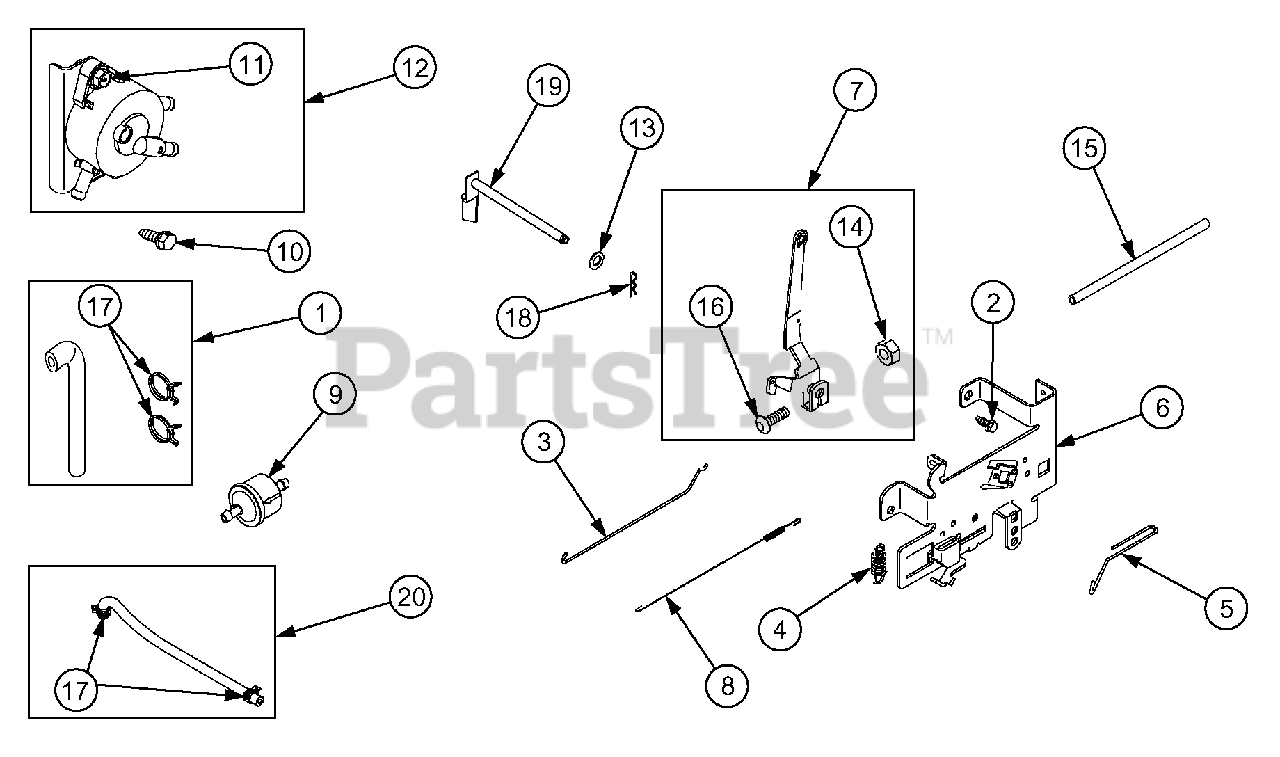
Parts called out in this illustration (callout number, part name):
1	Line, Fuel
2	Screw (Control Bracket)
3	Link, Mechanical Governor
4	Spring, Governor
5	Link, Choke
6	Bracket, Control
7	Control Lever, Governor
8	Spring, Governor Link
9	Filter, Fuel
10	Screw (Fuel Pump)
11	Screw (Fuel Pump)
12	Pump, Fuel
14	Nut (Governor Control Lever)
15	Shield, Cable
16	Bolt (Governor Control Lever)
17	Clamp, Hose
18	Pin, Cotter
19	Crank, Governor
20	Hose, Vacuum
